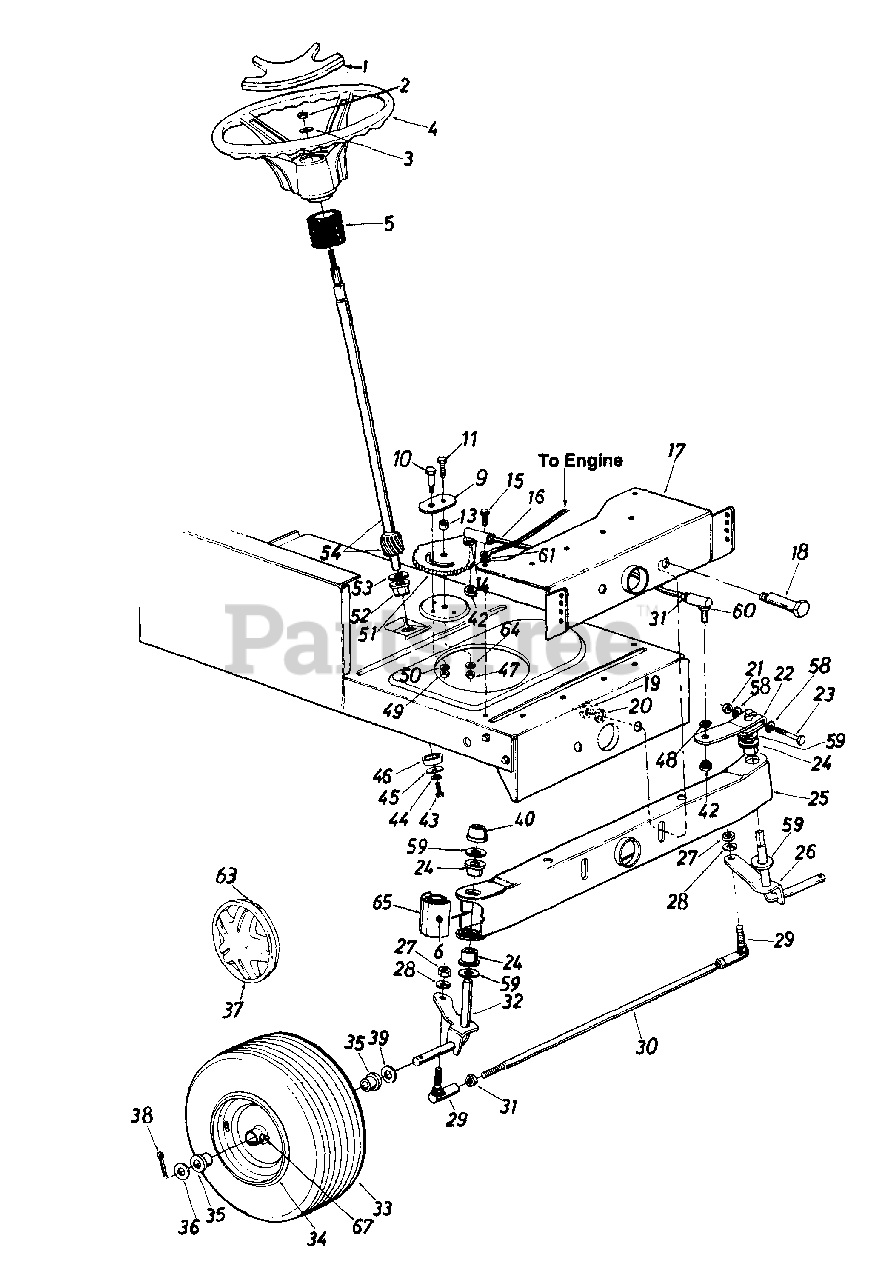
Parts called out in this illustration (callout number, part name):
1	Steering Wheel Cap
2	Hex L-Nut 5/16-24 Thd.
3	Belleville Wash. .345" I.D.
4	Steering Wheel
5	Steering Bellow - 9"
6	Grease Fitting
9	Retainer Plate
10	Shoulder Bolt .437" Dia. x .35" Lg. - 5/16-18 Thd.
11	Hex Bolt 3/8-24 x 1.0" Lg. (Grade 5)
13	Spacer .380" I.D. x .625" O.D. x .227
14	L-Wash. 3/8" I.D. (H.D.)
15	Hex Wash. Hd. Self-Tap Scr.
16	Steering Drag Link
17	Front Pivot Brkt.
18	Shoulder Bolt .498" Dia. x 2.04" Lg. - 3/8-16 Thd.
19	Hex Nut 3/8-16 Thd.
20	L-Wash. 3/8" I.D.
21	Hex L-Nut 5/16-24 Thd.
22	Steering Arm Front Axle
23	Hex Bolt 5/16-24 x 2.00" Lg. (Grade 5)
24	Hex Flg. Brg. .632 I.D.
26	Front Axle Ass'y. - L.H.
27	Hex Nut 3/8-24 Thd.
28	L-Wash. 3/8" I.D.
29	Ball Joint 3/8-24 Thd.
31	Hex Jam Nut 3/8-24 Thd.
32	Front Axle Ass'y. - R.H.
36	Fl-Wash. .635" I.D. x 1.59" O.D.
37	Front Wheel Hub Cap
38	Cotter Pin 1/8" Dia. x 1.25"
39	Fl-Wash. .640" I.D. x 1.24" O.D.
40	Push Cap 5/8" Dia. Rod
42	Hex Jam Nut 3/8-24 Thd.
43	Hex L-Bolt 5/16-18 x .62"
44	L-Wash. 5/16" I.D.
45	Fl-Wash. .33" I.D. x 1.25" O.D.
46	Spacer (Plastic)
47	Hex Cent. L-Nut 3/8-24 Thd.
48	L-Wash. 3/8" I.D.
49	Hex Cent. L-Nut 5/16-18 Thd.
50	L-Wash. 5/16" I.D.
51	Steering Gear Segment
52	Hex . Fig. Brg. .634 I.D.
53	Fl-Wash. (Hardened)
54	Steering Shaft
58	Wave-Wash. .32" I.D. x .62" O.D.
59	Fl-Wash. (Hardened)
60	Drag Link Ball Joint 3/8-24 Thd.
61	Ext. L-Wash. 5/16" I.D.
63	Spring Clip
64	Bell-Wash. .39" I.D. x 1.38" O.D.
65	Pivot Bar End Cap
67	Grease Fitting
